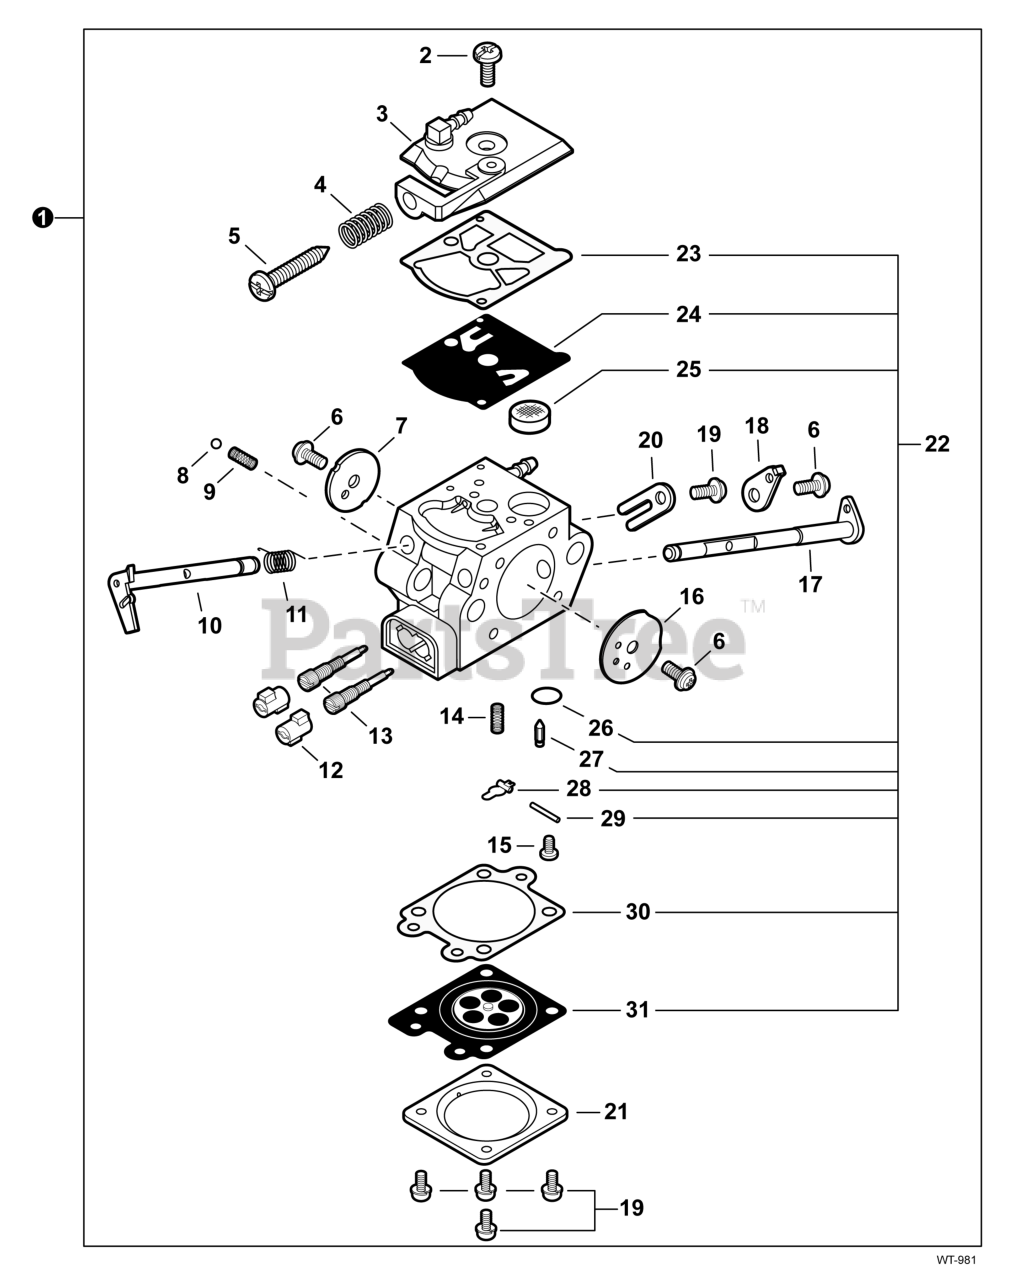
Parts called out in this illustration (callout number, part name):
1	CARBURETOR WT-981
3	COVER, FUEL PUMP
4	SPRING, IDLE ADJUST
5	SCREW, IDLE ADJUST
7	VALVE, THROTTLE
8	BALL, CHOKE FRICTION
10	SHAFT ASSY, THROTTLE
11	SPRING, THROTTLE RETURN
12	CAP, LIMITER
13	NEEDLE, MIXTURE
14	SPRING, METERING LEVER
15	SCREW, METERING LEVER PIN
16	VALVE, CHOKE
17	SHAFT, CHOKE
18	LEVER, THROTTLE
20	CLIP, THROTTLE SHAFT
21	COVER, METERING DIAPHRAGM
22	REPAIR KIT, CARBURETOR
23	GASKET, FUEL PUMP
24	DIAPHRAGM, PUMP
25	SCREEN, FUEL INLET
26	PLUG, WELCH
27	VALVE, INLET NEEDLE
28	LEVER, METERING
29	PIN, METERING LEVER
30	GASKET, METERING DIAPHRAGM
31	DIAPHRAGM, METERING
